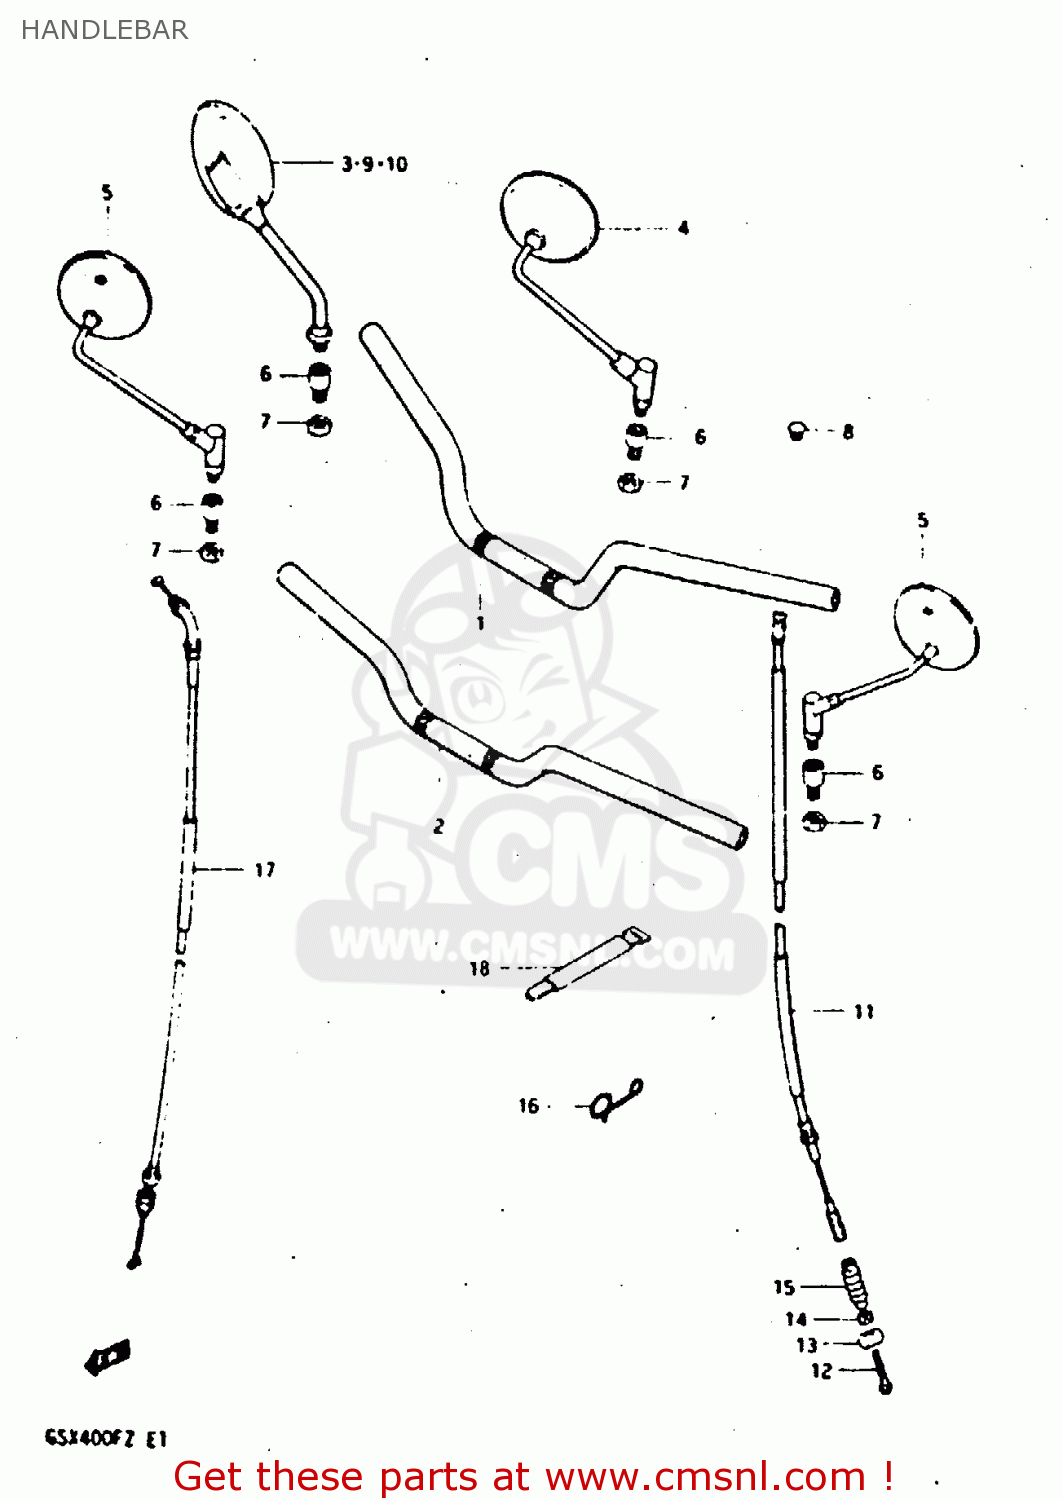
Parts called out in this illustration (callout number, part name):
1	HANDLEBAR (NEUTRAL)
2	HANDLEBAR
4	MIRROR ASSY,RR VIEW
6	CUSHION,REAR VIEW MIRROR
7	NUT
8	CAP(OD:14)
11	CABLE, CLUTCH (FLAT)
12	SCREW
13	PIN
14	NUT
15	DUST SEAL
16	GUIDE,CLUTCH CABLE
17	CABLE ASSY,THR
18	CLAMP
